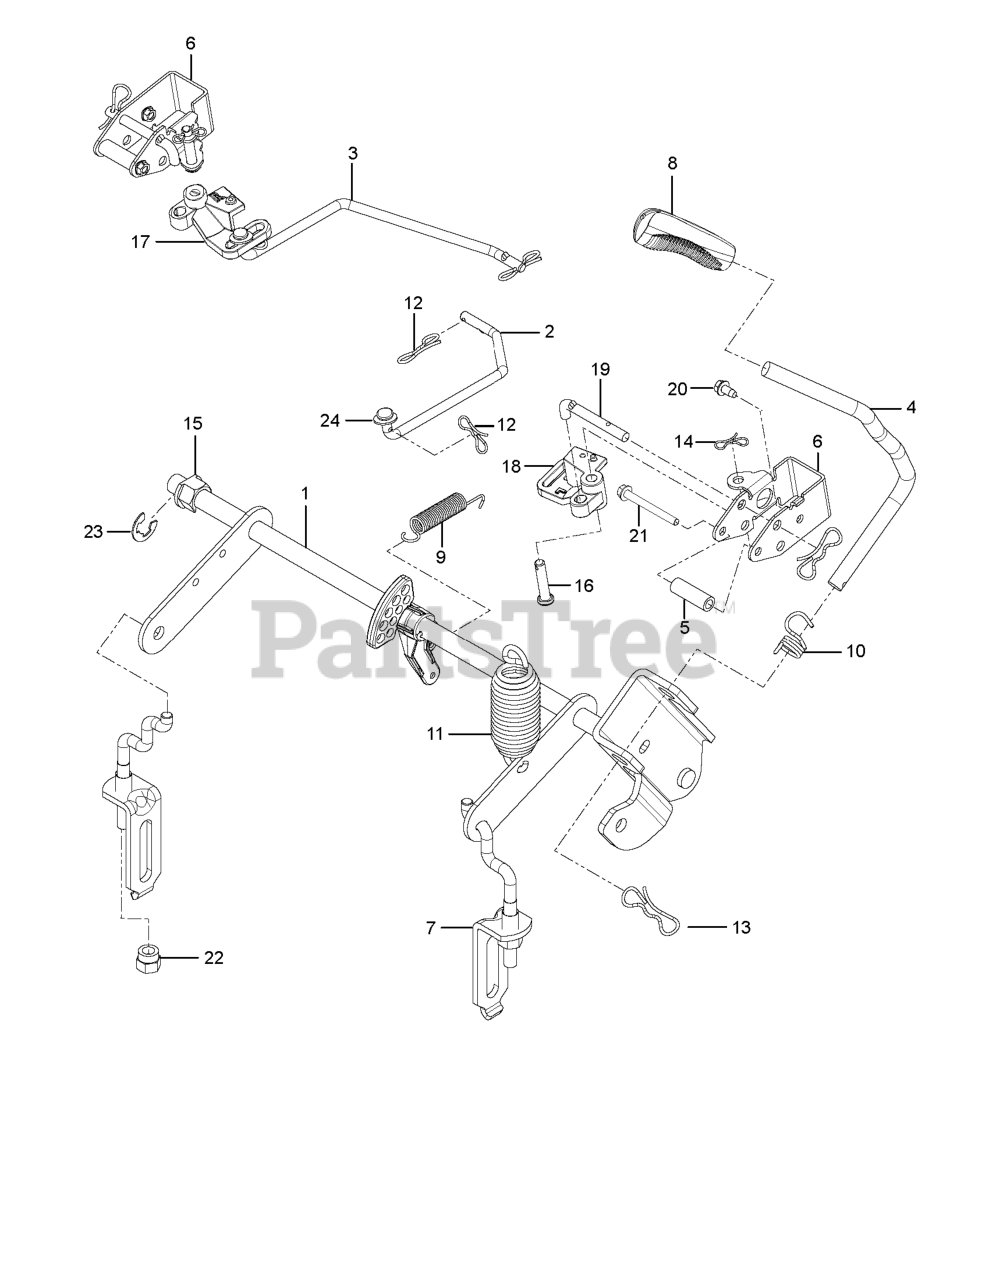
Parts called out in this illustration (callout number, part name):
1	SHAFT ASSY DECK LIFT WELDMENT
2	LINK.BRAKE.PARK.UPPER.LH
3	LINK.BRAKE.PARK.UPPER.RH
4	HANDLE LIFT ZTR
4	LIFT.LEVER.ASM.RZ.SERVICE
5	SPACER.334.ID.5.OD.1.5.L
6	BRACKET.BELLCRANK.PBRAKE X431
7	LINK, REAR SUSPENSION
8	GRIP.HANDLE.LIFT.PVC.BLACK
9	RETURN.BRAKE.PARK.AUTO
10	SPRING.TORSION.LIFT.HANDLE
12	PIN COTTER;LOCKING;BOWTIE;1IN
13	PIN.COTTER.7/16.BOW TI.
14	PIN.COTTER.5/16.BOW TI
15	PLASTIC NUT
16	PIN.5.16X1.5
17	BELLCRANK.RH
18	BELLCRANK.LH
19	ROD.PUSH.BRAKE
20	SCREW.1/4-20X5/8
21	SCREW THD;ROLL;1/4-20 X 2.25
22	NUT, LIFT LINK 7/16-20
23	RETAINING RING LT
24	WASHER
